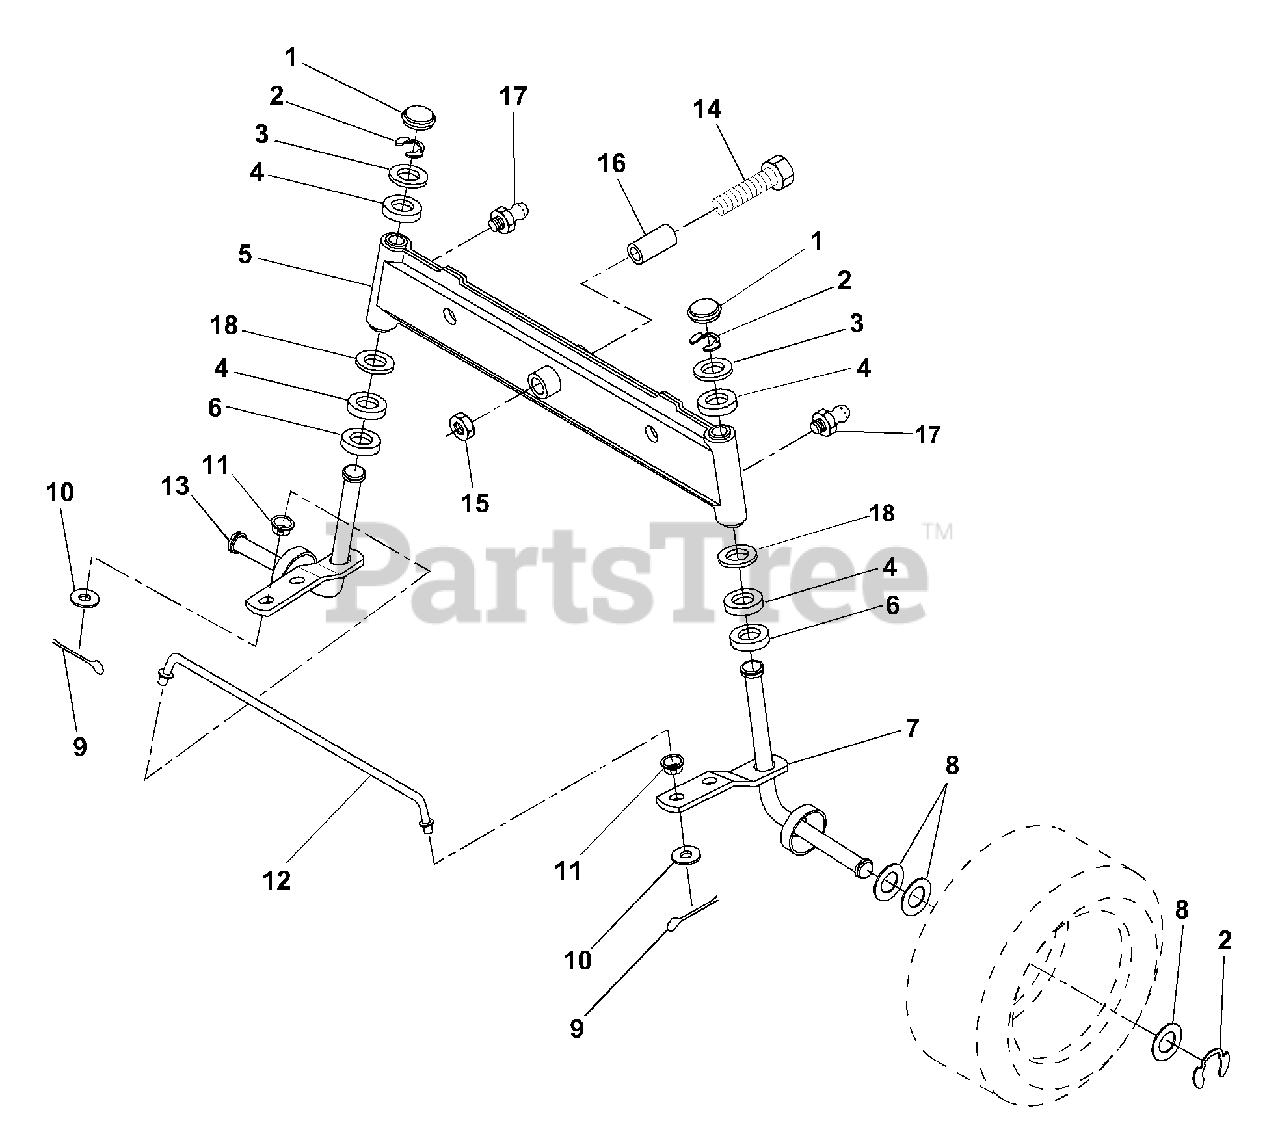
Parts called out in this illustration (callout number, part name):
1	Cap, Spindle
2	Ring, Clip
3	Washer 25/32 x 1-5/8 x 16 Ga.
4	Nyliner
5	Axle, Front
6	Bearing, Thrust
7	Spindle, R.H. Asm.
8	Washer 25/32 x 1-1/4 x 16 Ga.
9	Pin, Cotter 1/8 x 3/4
10	Washer 13/32 x 13/16 x 16 Ga.
12	Rod, Tie
13	Spindle, L.H. Asm.
14	Bolt Hex 5/1-11 x 3-1/2
15	Nut, Lock Flange 5/8-11
16	Spacer, Bearing Axle
17	Fitting, Grease
18	Washer 27/32 x 1-1/4 x 16 Ga.
